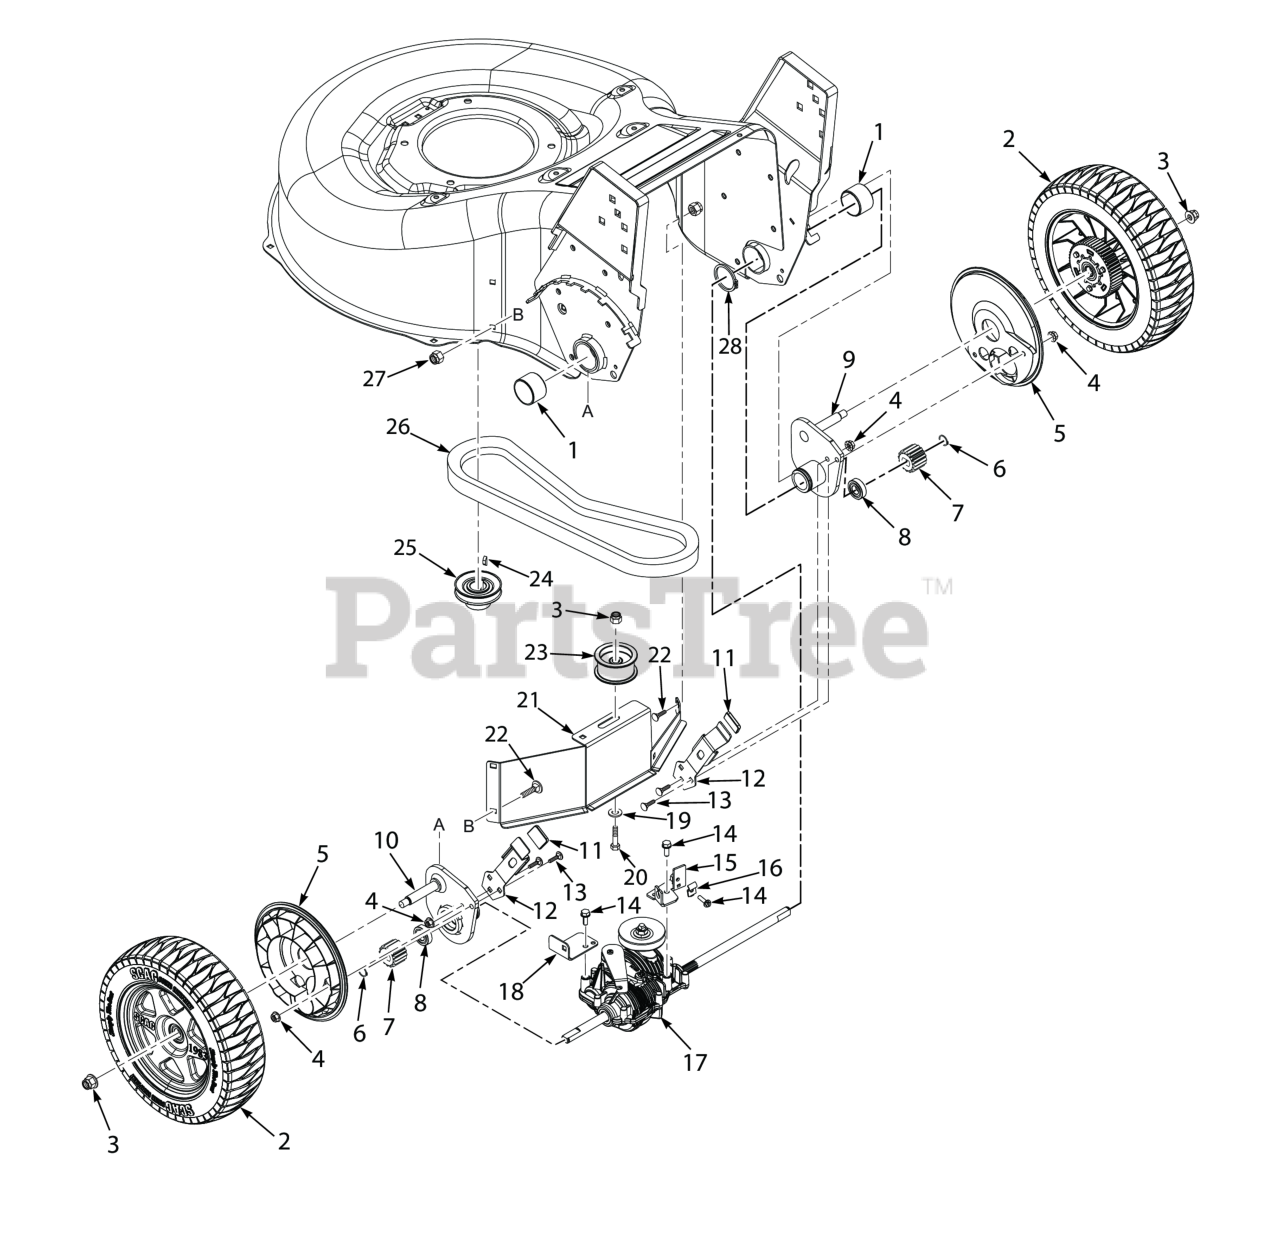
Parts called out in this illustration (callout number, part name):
1	Bearing
2	Wheel Assembly, Rear
3	Nut, Flange Elastic Stop Nut, 3/8-16
4	Nut, Flanged Elastic Stop 1/4-20
5	Cover, Rear Wheel
6	Retaining Ring, 1/2" Ext. HD
7	Gear, Pinion
8	Bearing (x2)
9	Wheel Axle Mount, RH
10	Wheel Axle Mount, LH
11	Grip, Deck Height
12	Adjust Lever, Rear
13	Serr. Fl. Hex Head CPSCR, 1/4-20 x 3/4"
14	Screw, M6-1.00 X 16 Shakeproof
15	Mount, Cable Weldment
16	Clamp, Cable
17	Transmission
18	Bracket, Transmission Mount
19	Flatwasher, 3/8 (.406 x .812 x .065)
20	Bolt, Hex Head 5/16-18 x 1-1/2" - Front
21	Baffle, Rear
22	Bolt, Carriage 1/4-20 x 1/2"
23	Pulley, 2.0 Idler
24	Pulley, Transmission
25	Key, 3/16 x 3/16 x .313
26	Belt, Transmission
27	Nut, Spiralock 3/8-16
28	Retaining Ring, 1-3/8" Ext. HD
